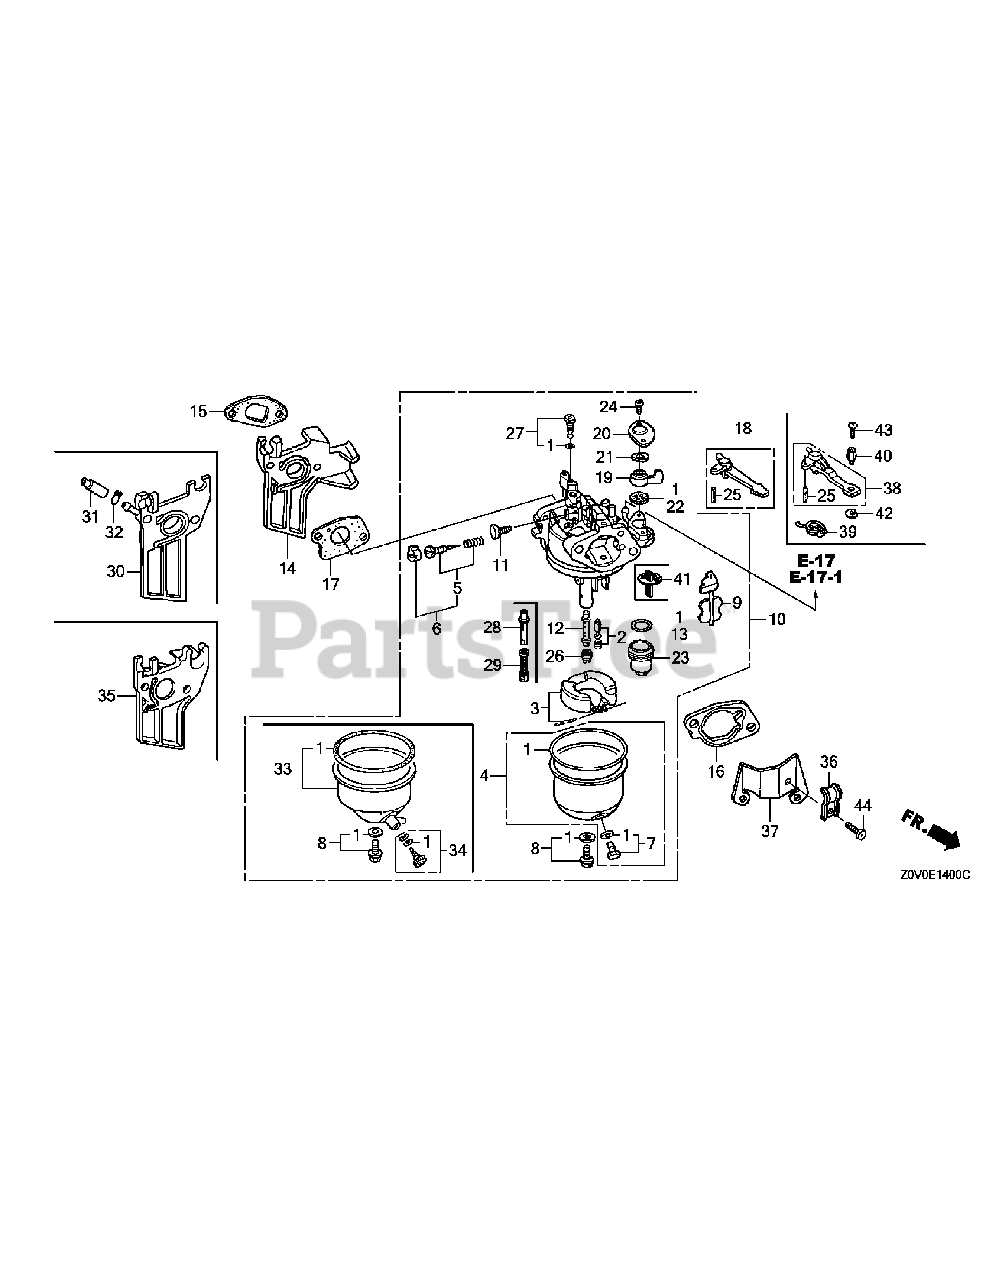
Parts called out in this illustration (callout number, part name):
1	Gasket Set
2	Valve Set, Float
3	16013-Z0S-B01 Float Set
4	Chamber Set, Float
5	Screw Set, Pilot
6	Screw Set, Pilot
7	Screw Set, Drain
10	Carburetor Assy.(Be59Q A)
11	Screw, Throttle Stop
12	Nozzle, Main
13	Packing, Fuel Strainer Cup
14	Insulator, Carburetor
15	Packing, Insulator
16	Spacer Comp., Carburetor
17	Packing, Carburetor
18	Lever Comp., Choke(Std.)
19	Lever, Cock
20	Plate, Lever Setting
21	Spring, Cock Lever
22	Packing, Fuel Cock
23	Cup, Fuel Strainer
24	Screw, Pan, 3X6
25	Pin, Spring, 2X12
26	Jet, Main, #70
26	Jet, Main, #72
26	Jet, Main, #75
26	Jet, Main, #68
27	Jet Set, Pilot, #40
28	Nozzle, Main
29	Porous, Nozzle
30	Insulator Comp., Carburetor
31	Cap, Boost
32	Clip, Tube(B7)
33	Chamber, Float
34	Screw Set, Drain
35	Insulator, Carburetor
36	Holder, Control Cable
37	Stay, Choke Control
38	Lever Comp., Choke(Remote)
39	Spring, Return
40	Holder, Cable
41	Filter, Cup
42	Circlip, 5Mm
43	Screw, Pan, 4X8
44	Screw, Pan, 5X8
